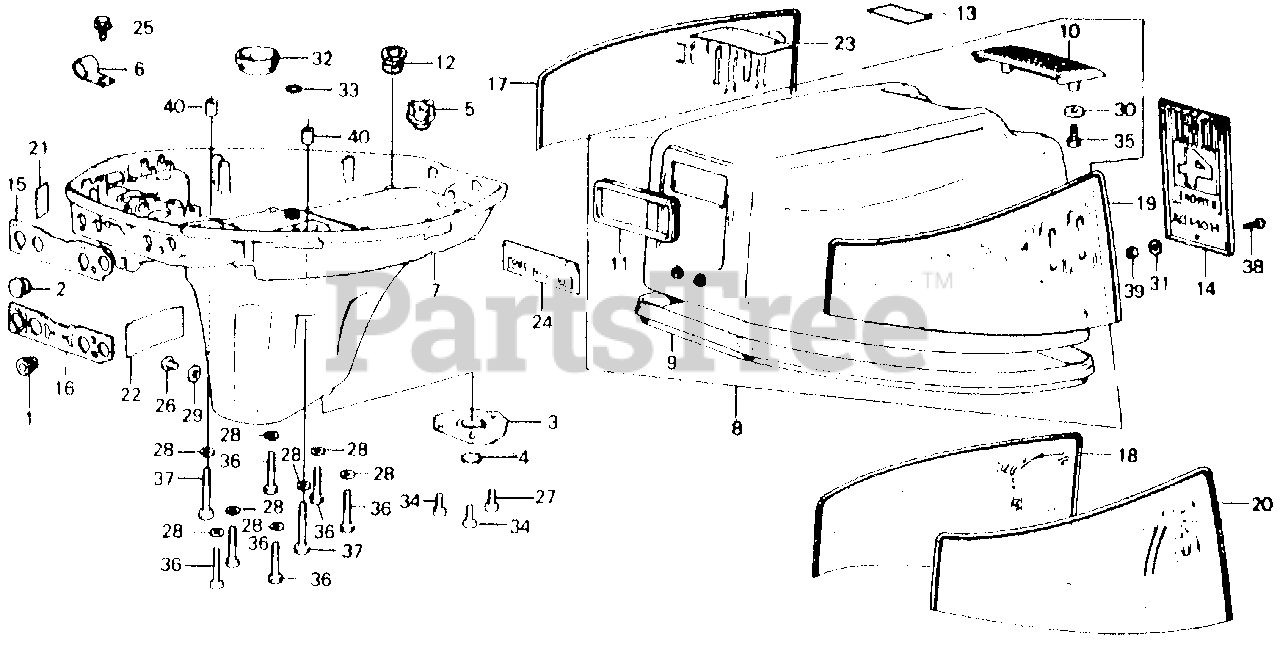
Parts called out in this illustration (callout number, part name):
1	GROMMET A, WIRE
2	GROMMET C, OIL CASE
3	PLATE, EX.
4	BAND, EX. SEAL
5	MANIFOLD, TUBE
7	CASE, OIL *B9* (ATLANTIS BLUE)
8	COVER, ENGINE *NH24* (CERAMIC WHITE) (NOT AVAILABLE)
9	SEAL, ENGINE COVER (NOT AVAILABLE)
10	HANDLE, TILT *NH24* (CERAMIC WHITE) (NOT AVAILABLE)
11	SEAL, RECOIL
13	MARK, INSTRUCTION
14	EMBLEM, RR. (NOT AVAILABLE)
16	LABEL, INDICATION (NOT AVAILABLE)
18	EMBLEM, R. SIDE COVER (NOT AVAILABLE)
20	EMBLEM, L. SIDE COVER (NOT AVAILABLE)
21	MARK, CHANGE (NOT AVAILABLE)
22	LABEL, OIL FILLER POSITION (NOT AVAILABLE)
23	MARK, STARTER CAUTION (NOT AVAILABLE)
24	MARK, FR. (NOT AVAILABLE)
25	BOLT, FLANGE (6X12)
26	BOLT, OIL CHECK
27	BOLT, HEX. (6X12)
28	WASHER, PLAIN (6MM)
29	WASHER, NYLON (8MM)
30	WASHER (6MM)
31	WASHER, LOCK (4MM) (NOT AVAILABLE)
32	SEAL, COUPLING (25X40X22) (NOK)
33	O-RING (9.8X1.9)
34	BOLT, HEX. (6X12)
35	BOLT, HEX. (6X16)
36	BOLT, HEX. (6X32) (NOT AVAILABLE)
37	BOLT, HEX. (6X40)
38	SCREW, PAN (4X10)
39	NUT, HEX. (4MM) (SOURCE: VINTAGE PARTS INC.)
40	PIN, DOWEL (8X14)
